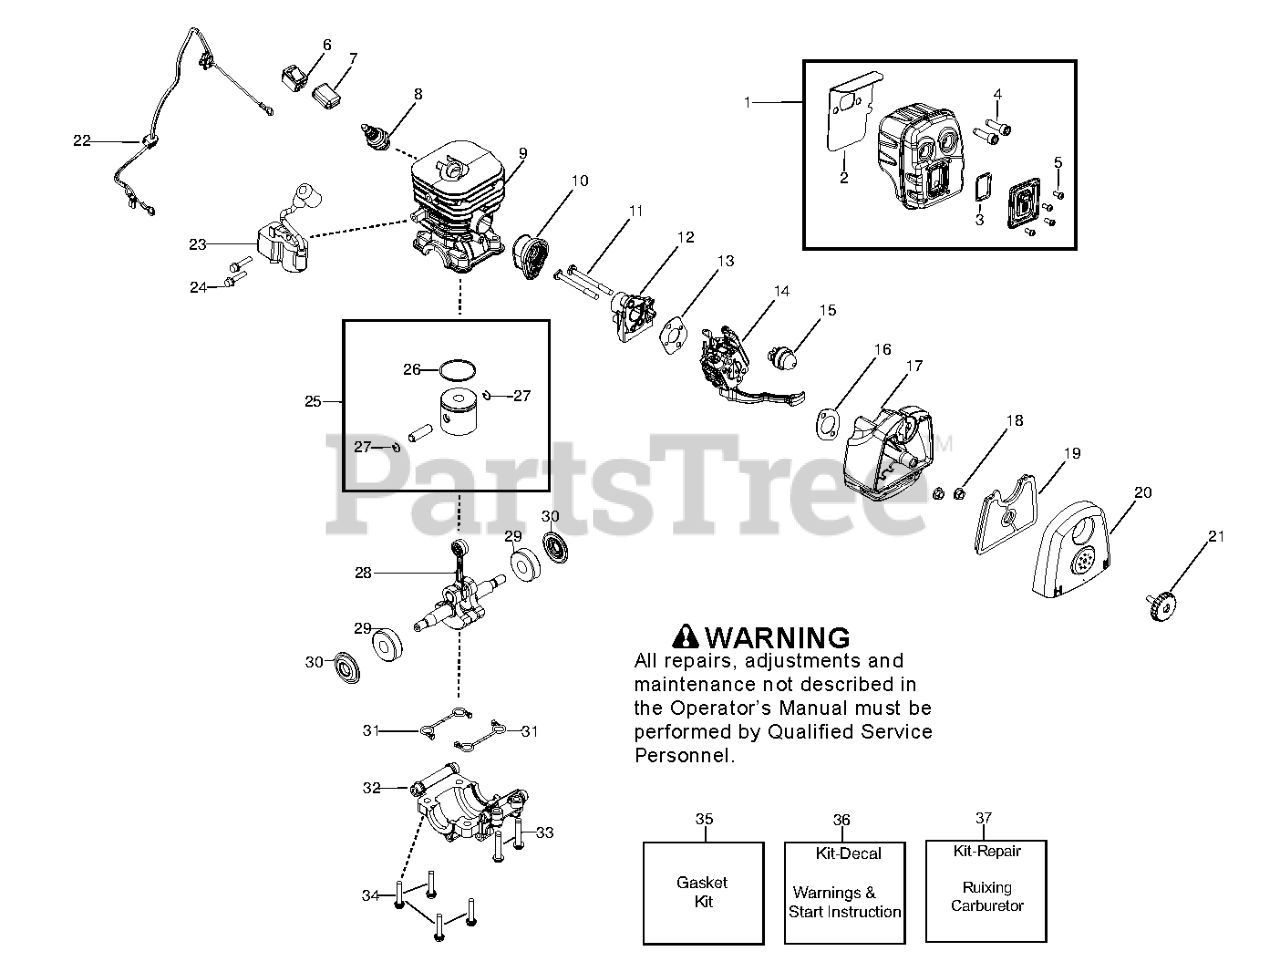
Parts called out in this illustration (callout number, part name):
1	ASSY MUFFLER
3	KIT, SPARK SCREEN
4	BOLT MUFFLER
5	SCREW-6-19X5/16PLAST PA
6	KIT SWITCH
7	PROTECTOR, SWITCH
8	Accy - Spark Plug (RCJ6-Y)
9	Cylinder
10	BOOT, CARB
12	PLATE, CARB
14	KIT CARBURETOR
17	BASE, AIRBOX
19	Air Filters
20	COVER, AIRBOX
21	KNOB ASSY AIRBOX COVER
22	ASSY, LEADWIRE
23	IGNITION MODULE
24	SCREW M4 X .70 TT 16MM
25	KIT - PISTON
26	RING PISTON
27	WRIST PIN RET.
29	BEARING RADIAL BALL (6201)
30	CRANKSHAFT SEAL
32	CAP - BEARING
34	SCREW-M5-0.8 X 25MM(TAP)
